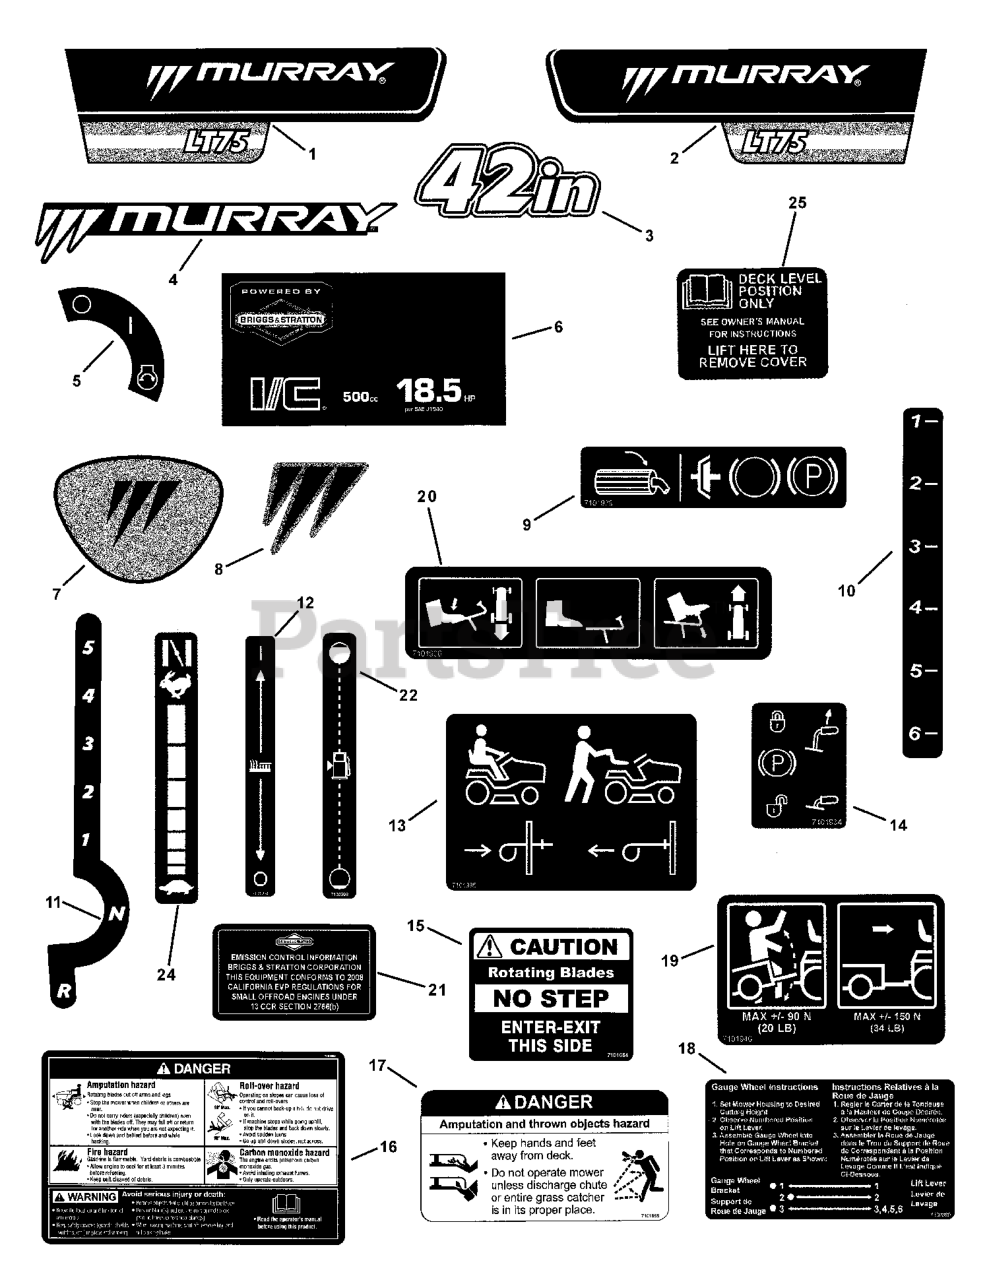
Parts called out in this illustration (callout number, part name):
1	MURRAY NAME PLATE, RH
2	MURRAY NAME PLATE, LH
3	42" Deck Decal, MURRAY
4	MURRAY NAME PLATE, Rear
5	DECAL, Ignition, RZT
6	DECAL, Briggs HP 18.5
7	DECAL, Steering Wheel Hub
8	DECAL, Front Hood
9	DECAL, Belt/Clutch
10	DECAL, Cutting Height, MURRAY
11	DECAL, Manual Drive
12	DECAL, Manual PTO
13	DECAL, Roll Release
14	DECAL, Park Brake
15	DECAL, No Step
16	DECAL, Umber
17	DECAL, Danger Do Not Operate w/o Deflector
18	DECAL, Gage Wheel Leveling
19	DECAL, Weight Limitation
20	DECAL, Drive Pedal
21	LABEL, Emissions, Small Volume Exemption
22	DECAL, Fuel Gage Long
24	DECAL, Throttle White/Black
25	DECAL, Deck Level
